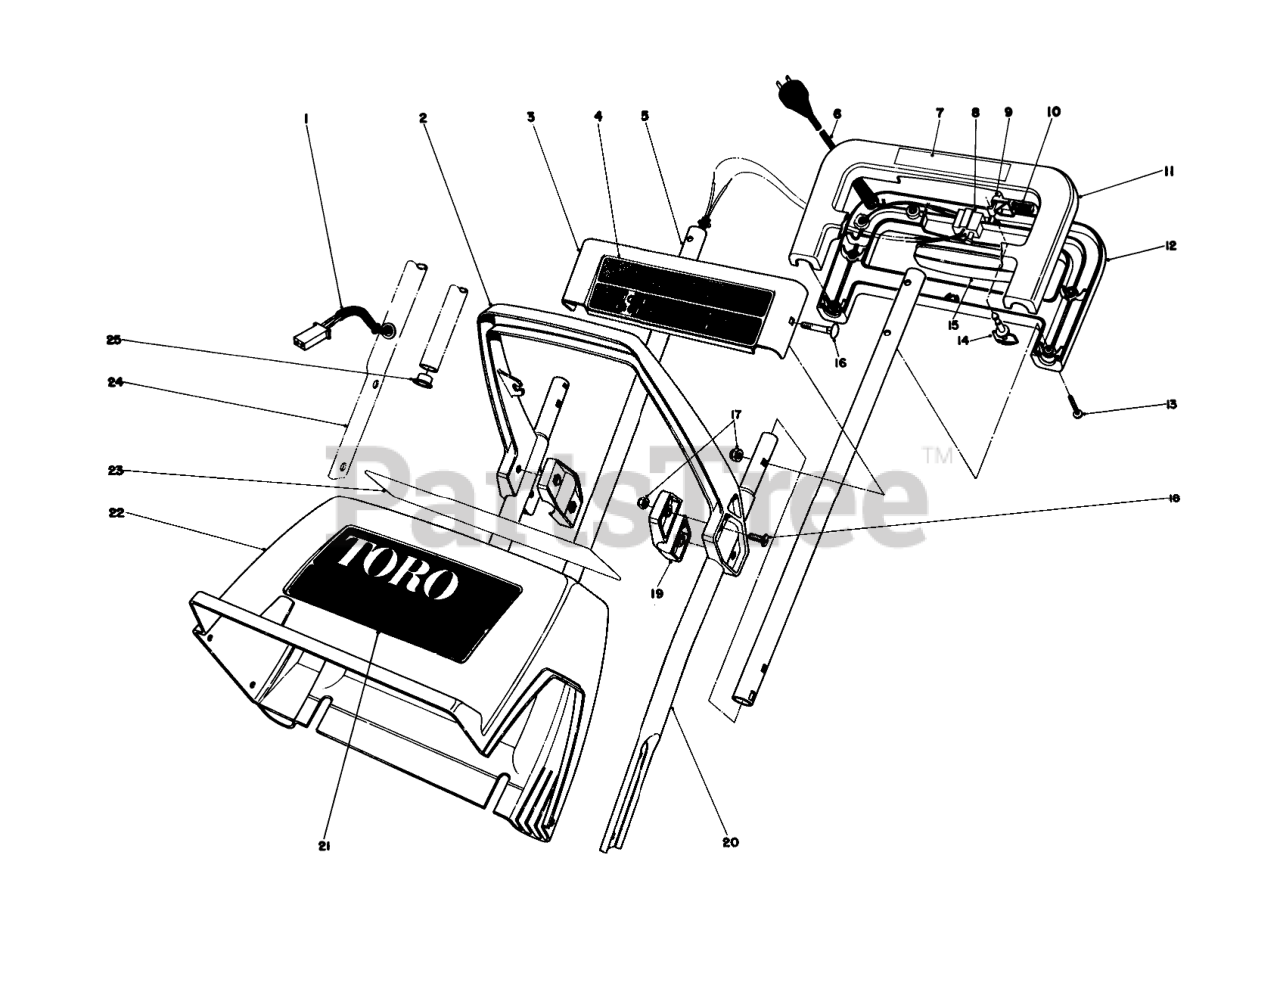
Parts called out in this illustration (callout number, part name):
8	SWITCH-STARTER
15	SWITCH BAR, 1200 PC
17	NUT-LOCK, NI
20	LOWER TUBE, LH, S-120
